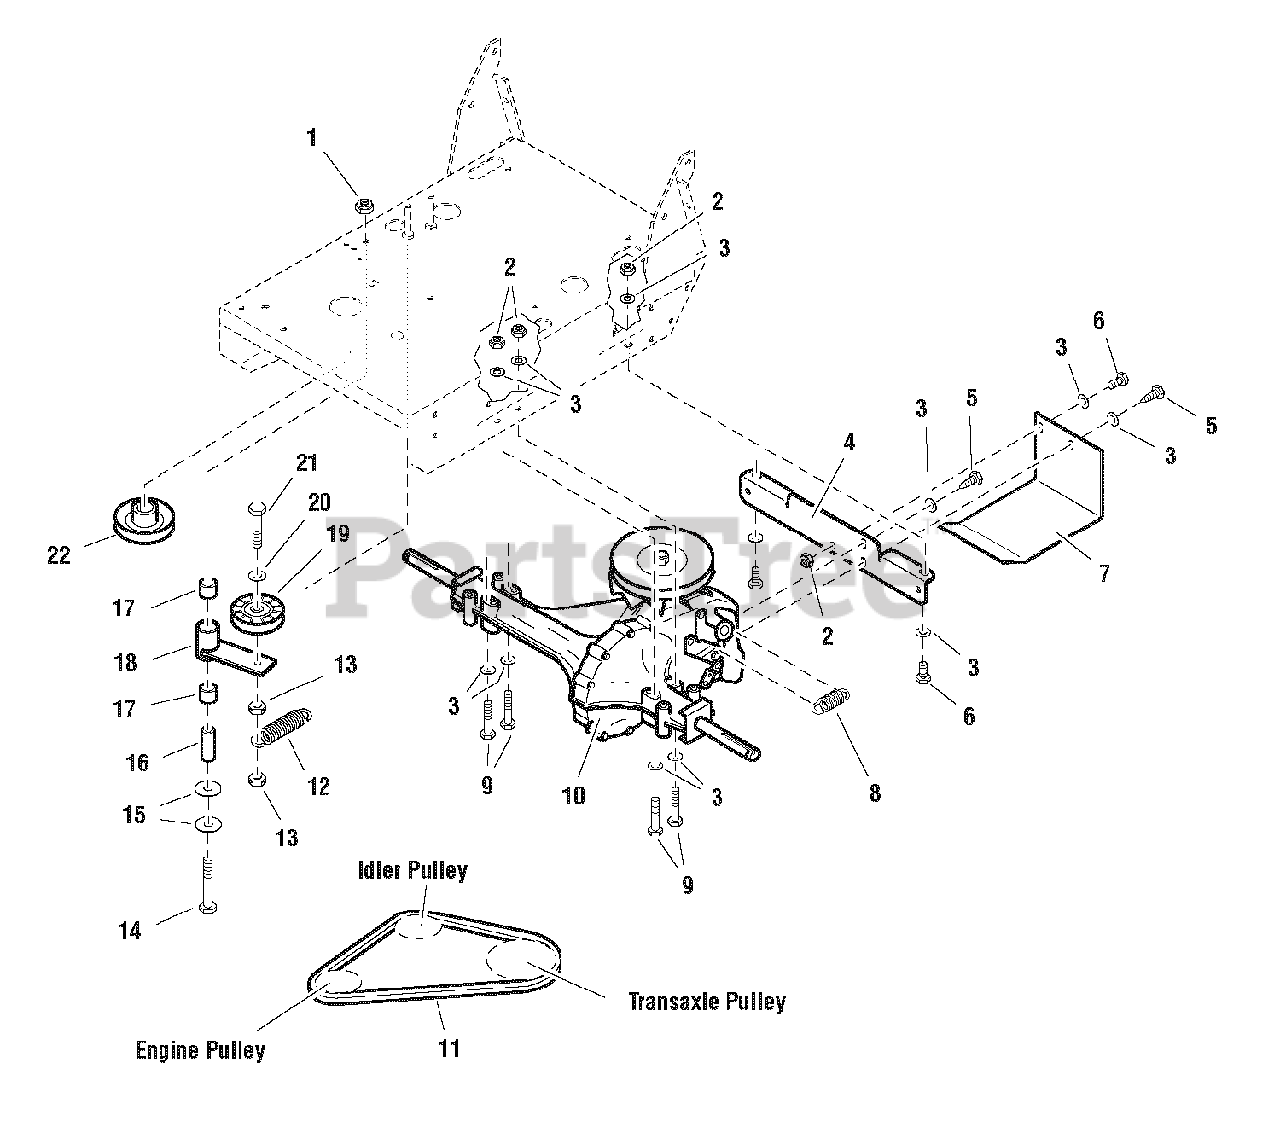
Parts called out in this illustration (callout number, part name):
1	NUT, Hex Nylon Lock, 3/8-16
2	NUT, Hex Nylon Lock, 5/16-18
3	WASHER, 5/16
4	TRANSAXLE BRACE
5	CAPSCREW, Hex Head, Self-Tapping, 5/16-18 x 3/4
6	BOLT, 5/16-18 X 3/4 GD5
7	SKID PLATE
8	HYDRO RETURN SPRING
9	CAPSCREW, Hex Head, 5/16-18 x 3
10	HYDROSTATIC TRANSAXLE
11	BELT
12	SPRING, Extension
13	NUT, Hex Side Lock, 3/8-16
14	BOLT, 3/8-16 X 3" GD5 CZ
15	WASHER, Fender, 3/8
16	SPACER
17	BUSHING, Brass
18	TRANSAXLE IDLER ARM
19	IDLER PULLEY ASSEMBLY
20	WASHER, 3/8
21	BOLT, 3/8-16 X 2, GD5, CZ
22	TRANSAXLE DRIVE PULLEY
